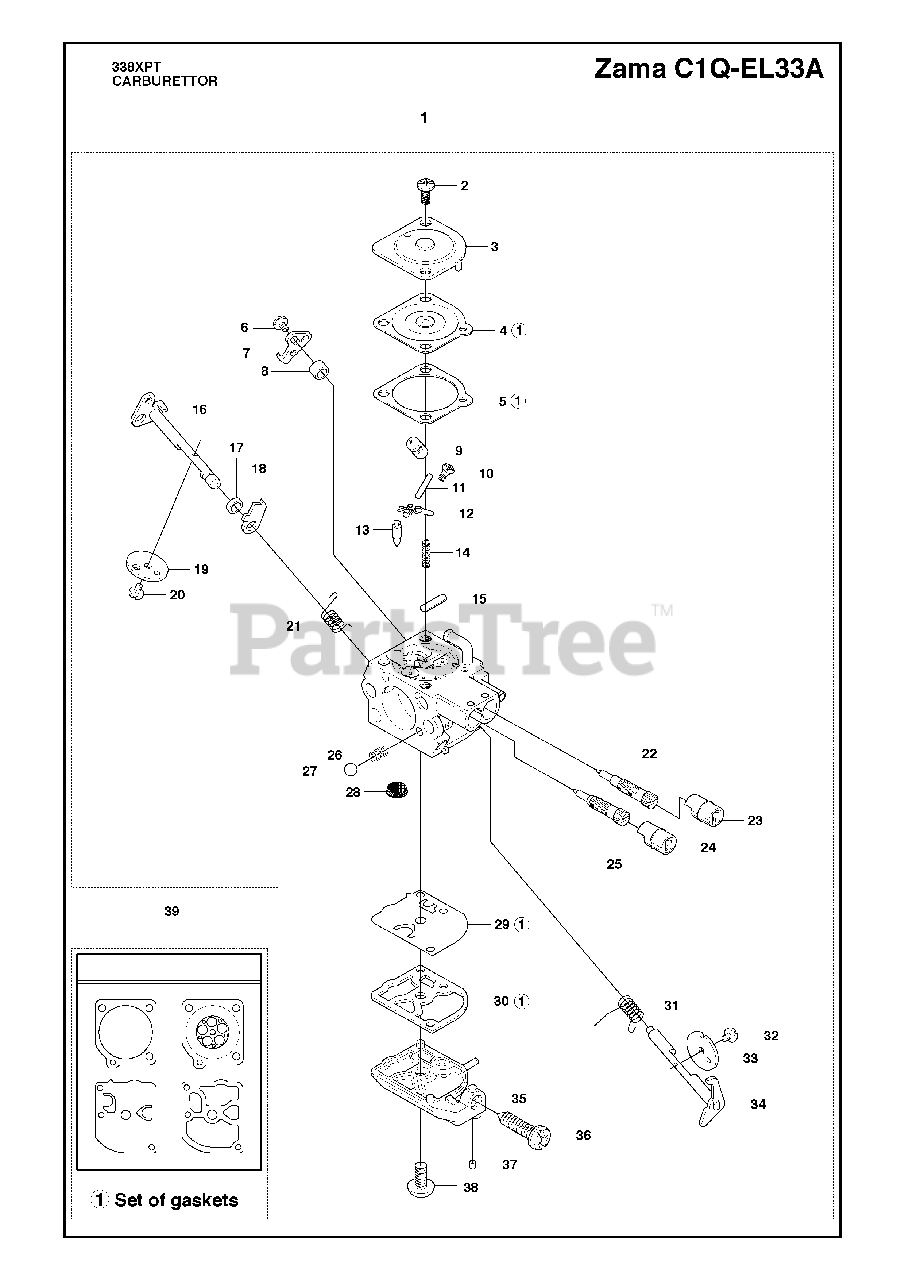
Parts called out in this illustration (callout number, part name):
1	CARBURETOR
11	PIN FULCRUM
13	INLET NEEDLE
19	CHOKE FLAP
22	IDLE SCREW
23	LIMITER CAP KIT
24	LIMITER CAP KIT
25	SCREW
29	PUMP DIAPHRAGM
31	SPRING THROTTLE
33	THROTTLE FLAP
39	GASKET KIT (ZAMA GND39)
